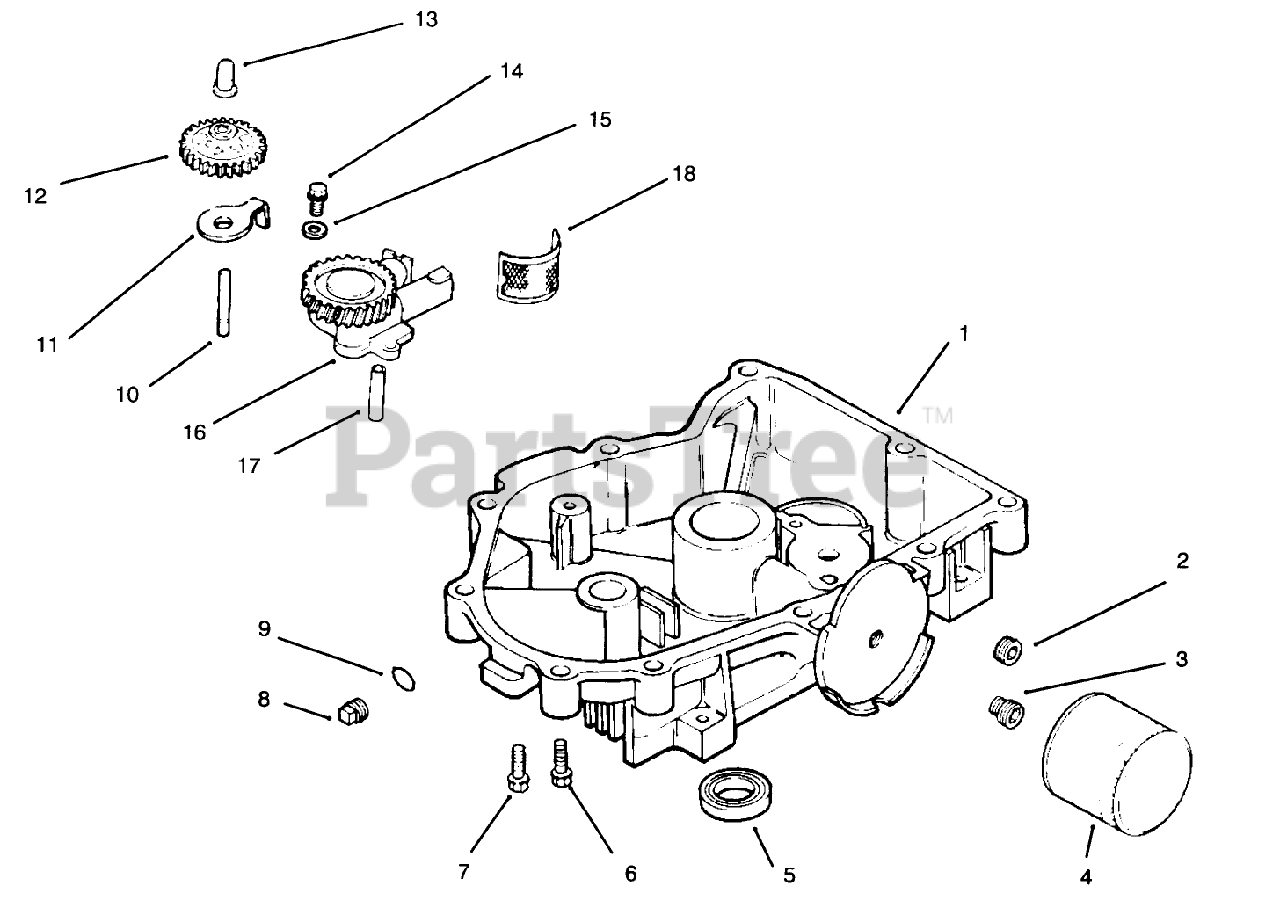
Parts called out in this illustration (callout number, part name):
1	Pan-Oil
2	Plug
3	Nipple-Filter, Oil
4	Filter-Oil
5	Seal-Oil
6	Screw
7	Screw
8	Plug
9	O Ring
10	Shaft-Gear, Governor
11	Tab-Locking
12	Kit-Governor Gear (Incl. Ref. #13)
13	Pin-Governor
14	Screw
15	Washer
16	Oil Pump Assembly (Incl. Ref. #17)
17	Tube-Oil Pickup
18	Screen-Oil
